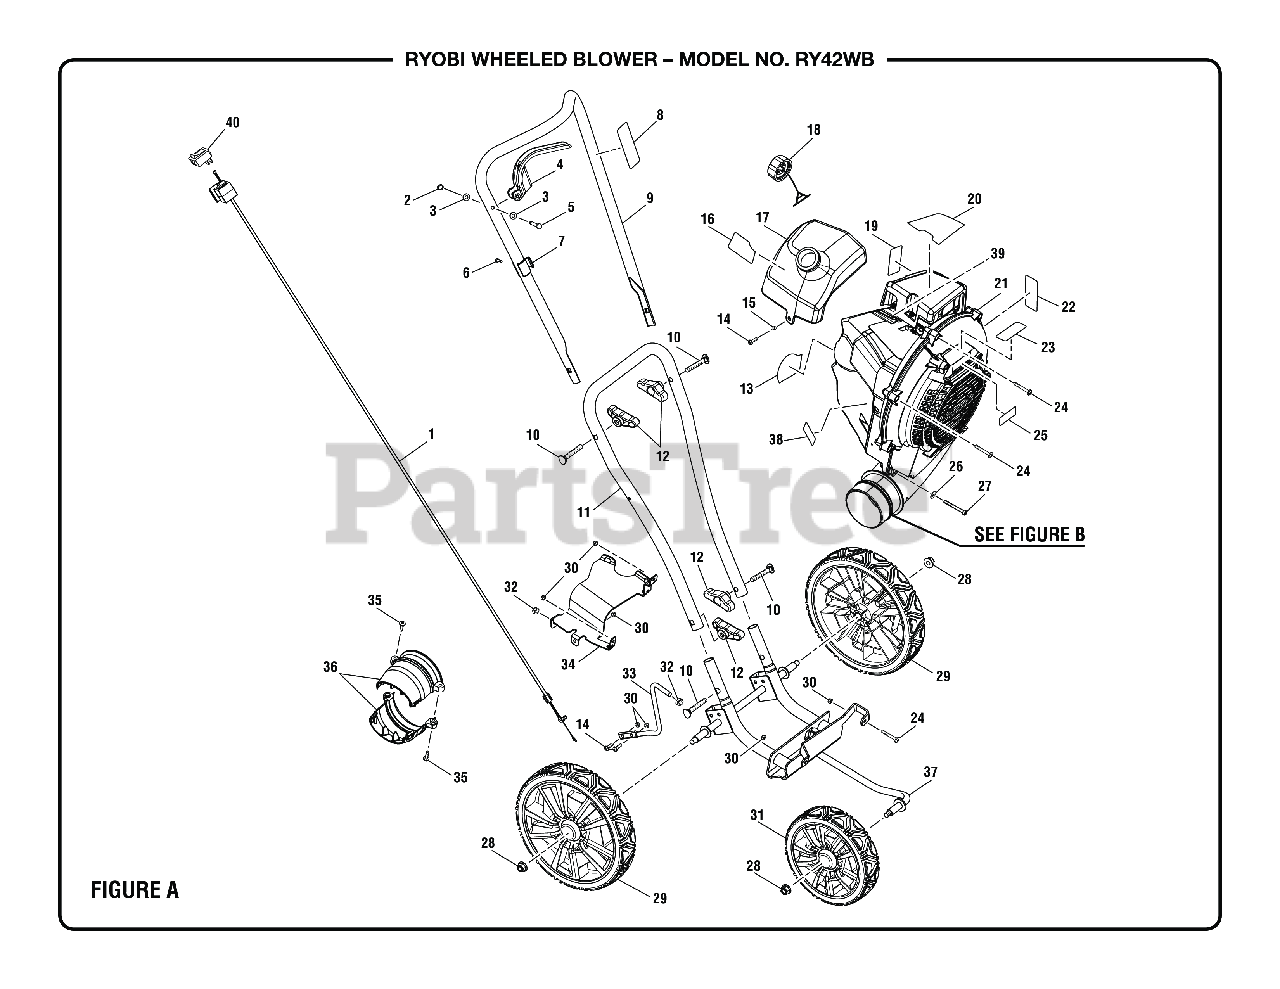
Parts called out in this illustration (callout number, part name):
1	Lead Wire and Throttle Cable Assembly
2	RETAINING RING
3	Fiber Washer (OD12.5 x ID6.35 x 2t)
5	Throttle Lever Pin
6	Screw (#8-16 x 1/2 in., Tri-Lobular)
7	Cable Clip
8	Warning Icon Label (Handle)
9	Upper Handle Assembly
10	Carriage Bolt (M8 x 60 mm)
11	Center Handle
12	Knob w/Nut Assembly
13	Model/Performance Label
14	Screw (M5 x 16 mm, T25 Torx Pan Hd.)
16	E85 Label
17	Fuel Tank Assembly
18	Fuel Cap Assembly (Inc. Tether)
19	Choke Label
20	Starting Instructions Label
21	Power Head Assembly
22	Hot Surface Label
23	Warning Icon Label (Inlet)
24	Screw (M5 x 35 mm, T25 Torx Pan Hd.)
25	Logo Label (Ryobi)
26	Washer (OD14 x ID5.1 x 1.4t)
27	Cap Screw (M5 x 45 mm, T25 Torx Soc. Hd.)
28	Lock Nut (3/8-16, Flange)
29	Rear Wheel Assembly
30	Lock Nut (M5 x 0.8 mm)
31	Front Wheel Assembly
32	Lock Nut (M8)
33	Support Rod
35	Screw (10-14 x 19 mm, T25 Torx Truss Pan Hd. T.F.)
37	Frame Assembly
38	Warning Label (Combustion)
39	Fuel Line Padding
40	Stop Switch (Momentary Contact)
